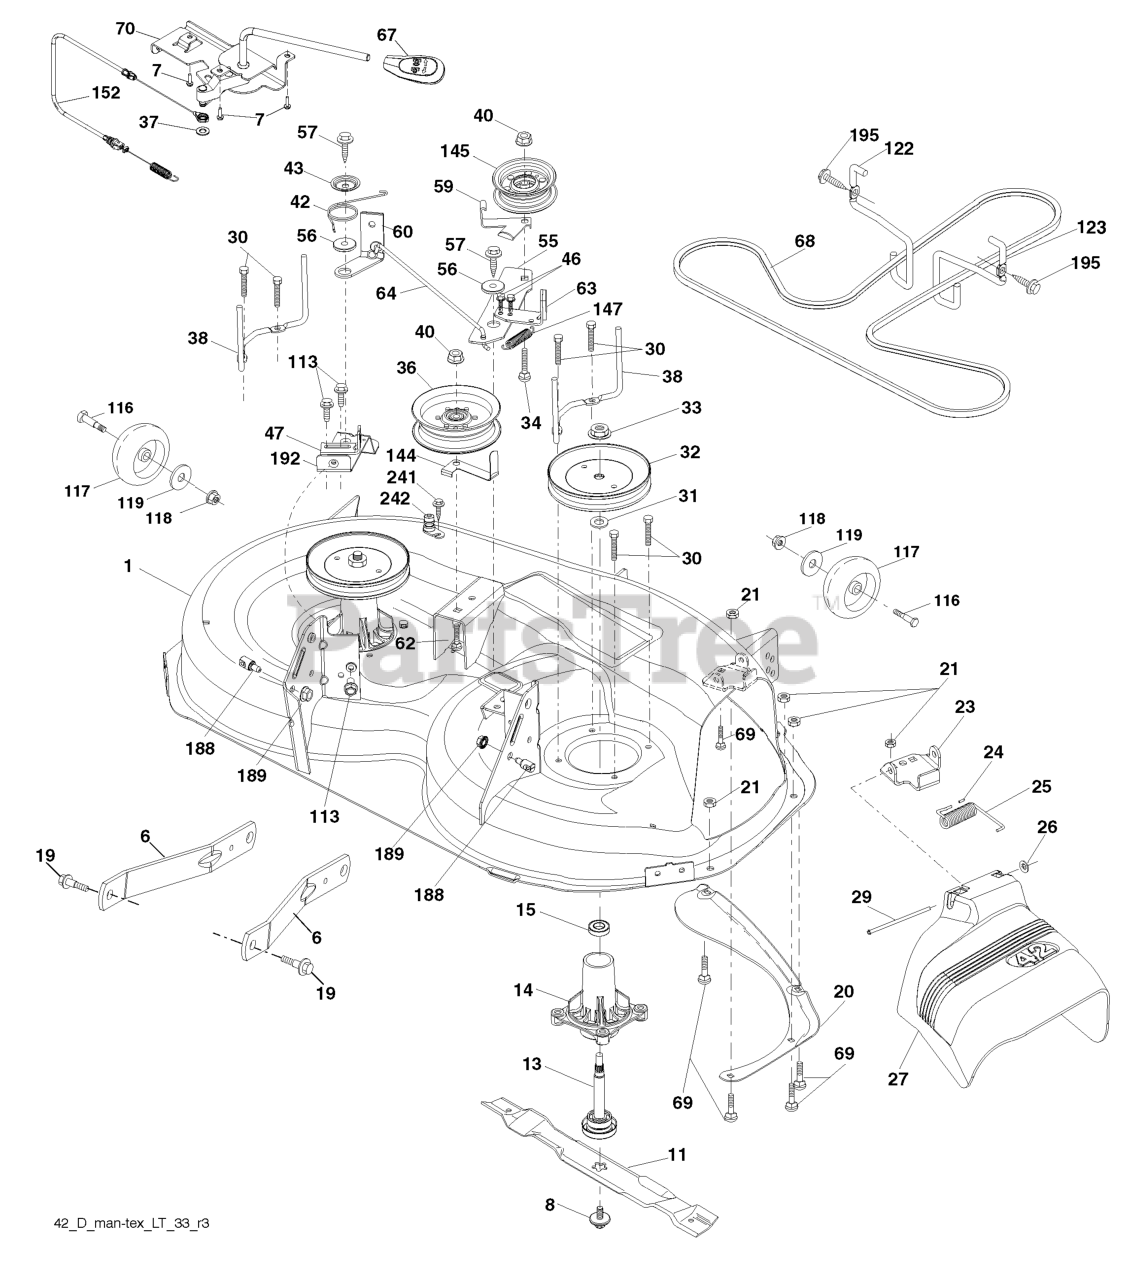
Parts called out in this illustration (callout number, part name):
1	DECK.WELDMENT.42"PAINT
6	ARM.SUSPENSION.MOWER.R
7	SCREW.#10 X 0.750.BOS
8	BOLT.WASHER.ASM.7/16-2
11	42" HI-LIFT BLADE
13	SHAFT.ASM.MDRL.N/GREASE.38
14	RP.HOUSING.MANDREL.4PT.
19	BOLT.SHOULDER
20	BAFFLE.VORTEX
21	LOCKNUT
23	BRKT.DEFLECTOR.38"2005+
24	CAP-SLEEVE LT
25	SPRING.TORSION.DEFLECT
26	NUT PUSH M
27	SHIELD.DEFLECTOR.MOWER.42"BLAC
29	ROD.HINGE
30	SCREW, WASHER HEAD
31	WASHER.SPACER.MANDREL
32	PULLEY.MANDREL.5.438.PD
33	NUT.FLANGE.LOCK.TOP
34	BOLT.3/8-16X1.50
36	PULLEY.IDLER.2006
37	WASHER
38	KEEPER.BELT.MANDREL.PULLEY
40	NUT LOCK FLG 3/8-16 UNC
42	SPRING.TORSION.BRAKE
43	SRPING.TORSION.RETAINE
46	SCREW.1/4-20X5/8
47	BRKT.CLUTCH.CABLE
55	IDLER.ARM
56	SPACER.RETAINER
57	SCREW 3/8-16X1
59	GUARD, BELT
60	ARM BRAKE MOWER
62	BOLT
63	ARM BRAKE MOWER
64	LINKAGE.BRAKE.ASM.ZINC
67	HANDLE.CLUTCH.CABLE.LT
68	BELT.DECK.DRIVE.42"
69	BOLT
70	CLUTCH.ASM.CABLE.HUSQ.TEX
113	BOLT.5/16HEX.WHS.HD
116	BOLT M
117	WHEEL.GAGE.HALF.SPOKED
118	LOCKNUT
119	WASHER.5/16.FLAT.STE.STD.
122	KEEPER BELT ENGINE LH
123	KEEPER BELT RH
144	KEEPER.BELT.MOWER
145	PULLEY.IDLER.48"PRIMARY
147	RETURN SPRING
152	CABLE.CLUTCH.CABLE.W/SPRING
188	STUD.FASTNER.W/ANTI-ROTATE
189	NUT LOCK HEX FLANGE 5/16-18
192	BRKT.BRAKE.STAND.LH.
195	SCREW, 3/8-16X3/4
241	SCREW.TT.#10-32X.5.3/8.FLANGE
242	PORT.WASHOUT
